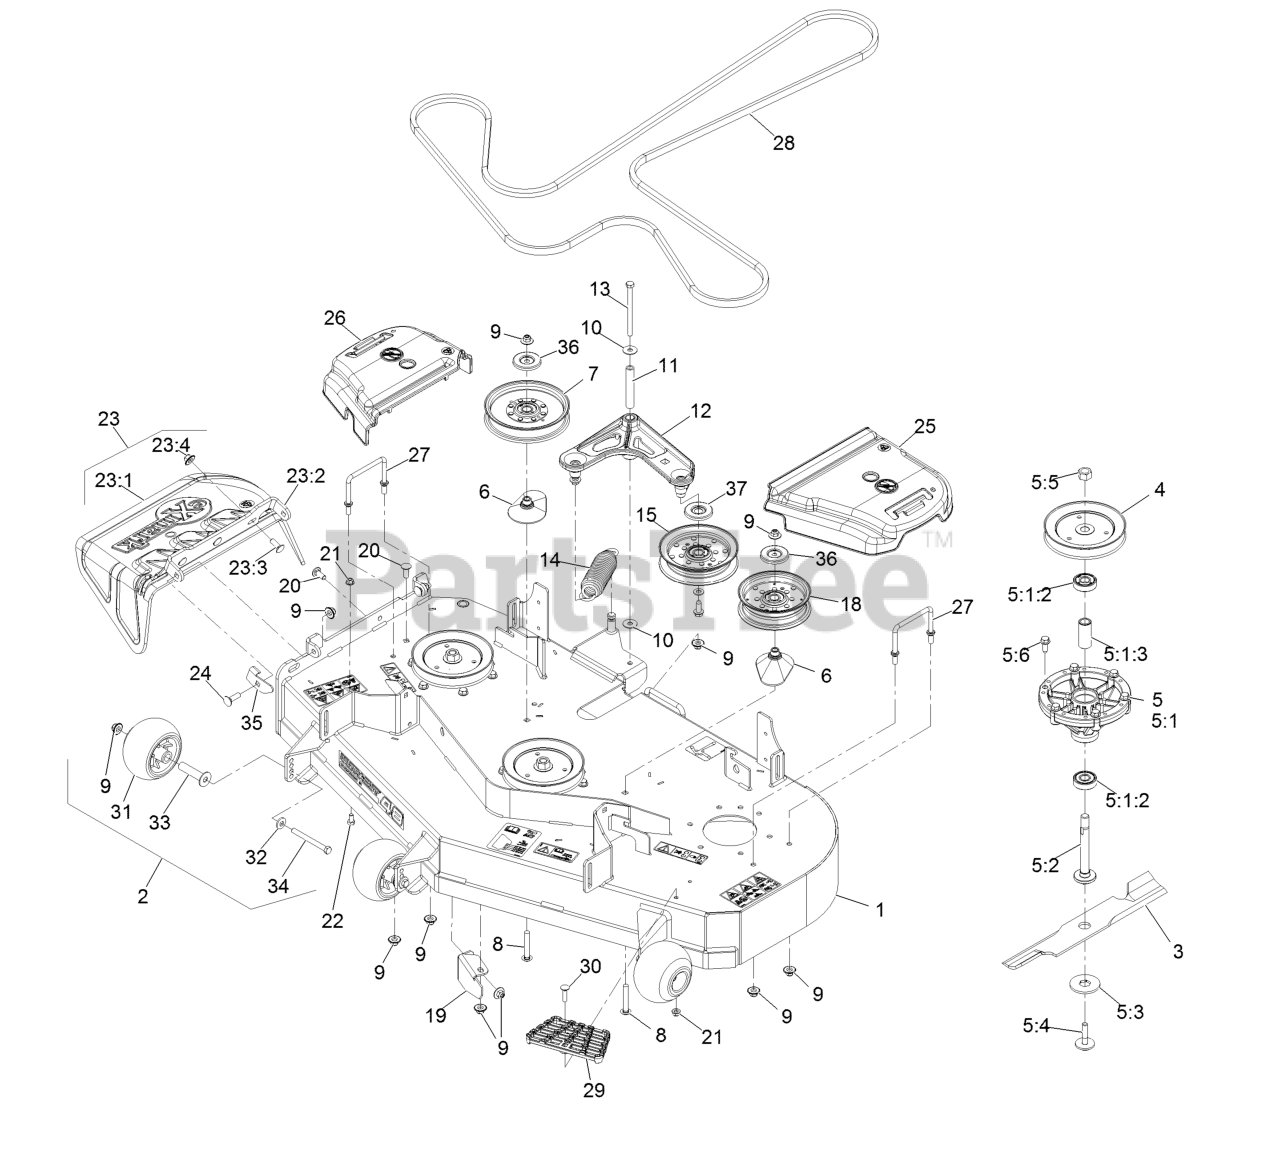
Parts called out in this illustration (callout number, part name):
1	ASM-Deck W/Decals 483
2	Kit, Anti-Scalp Roller
3	Blade, Mulching
3	Blade, Low Lift
3	Blade, Solid
3	Blade-Notched
3	Blade-Extreme 2, 16.25"
4	Sheave,Blade Drive 5.90
5	ASM, Cutter Housing Complete
5:1	ASM-Cutter Housing
5:1:2	Bearing
5:1:3	Spacer-Bearing
5:2	Spindle-Hex Pilot
5:3	Washer-Hex Blade Drive
5:4	Bolt-Blade, Sem
5:5	Nut-Hex 5/8-18
5:6	Screw-Forming, Thread
6	Spacer-Pulley
7	Idler-Pulley, Flat 6.00X1.00
8	Bolt-Carriage 3/8-16 X 2 1/2
9	Nut-Nyloc 3/8-16 Flg
11	Bushing
12	Idler Arm ASM
13	Screw-HH 3/8-16 X 4 3/4
14	Spring-Extension
15	Idler-Pulley, Flat
18	Idler-Pulley, Flat 5.00X1.31
19	Baffle,Discharge 483
20	Bolt-Carriage 3/8-16 X 1
21	Nut-Nyloc 5/16-18 Flg
22	Screw-HH 5/16-18 X 5/8
23	ASM,Discharge Chute
23:1	Chute, Discharge
23:2	Bracket,Discharge Chute
23:3	Bolt-Carriage 3/8-16 X 1
23:4	Nut-Nyloc 3/8-16 Flg
24	Bolt-Carriage 3/8-16 X 1 1/4
25	Cover-Belt, LH
26	Cover-Belt, RH
27	Wireform-Cover
28	Belt-V
29	Step-Deck
30	Bolt-Carriage 5/16-18 X 1 1/4
31	Roller-Anti-Scalp
32	Washer-Spring Disc 3/8
33	Axle, Roller
34	Screw-HH 3/8-16 X 3 3/4 GR 8
35	Stop-Discharge Chute
36	Shield-Dust
37	Shield-Guard, Dust
